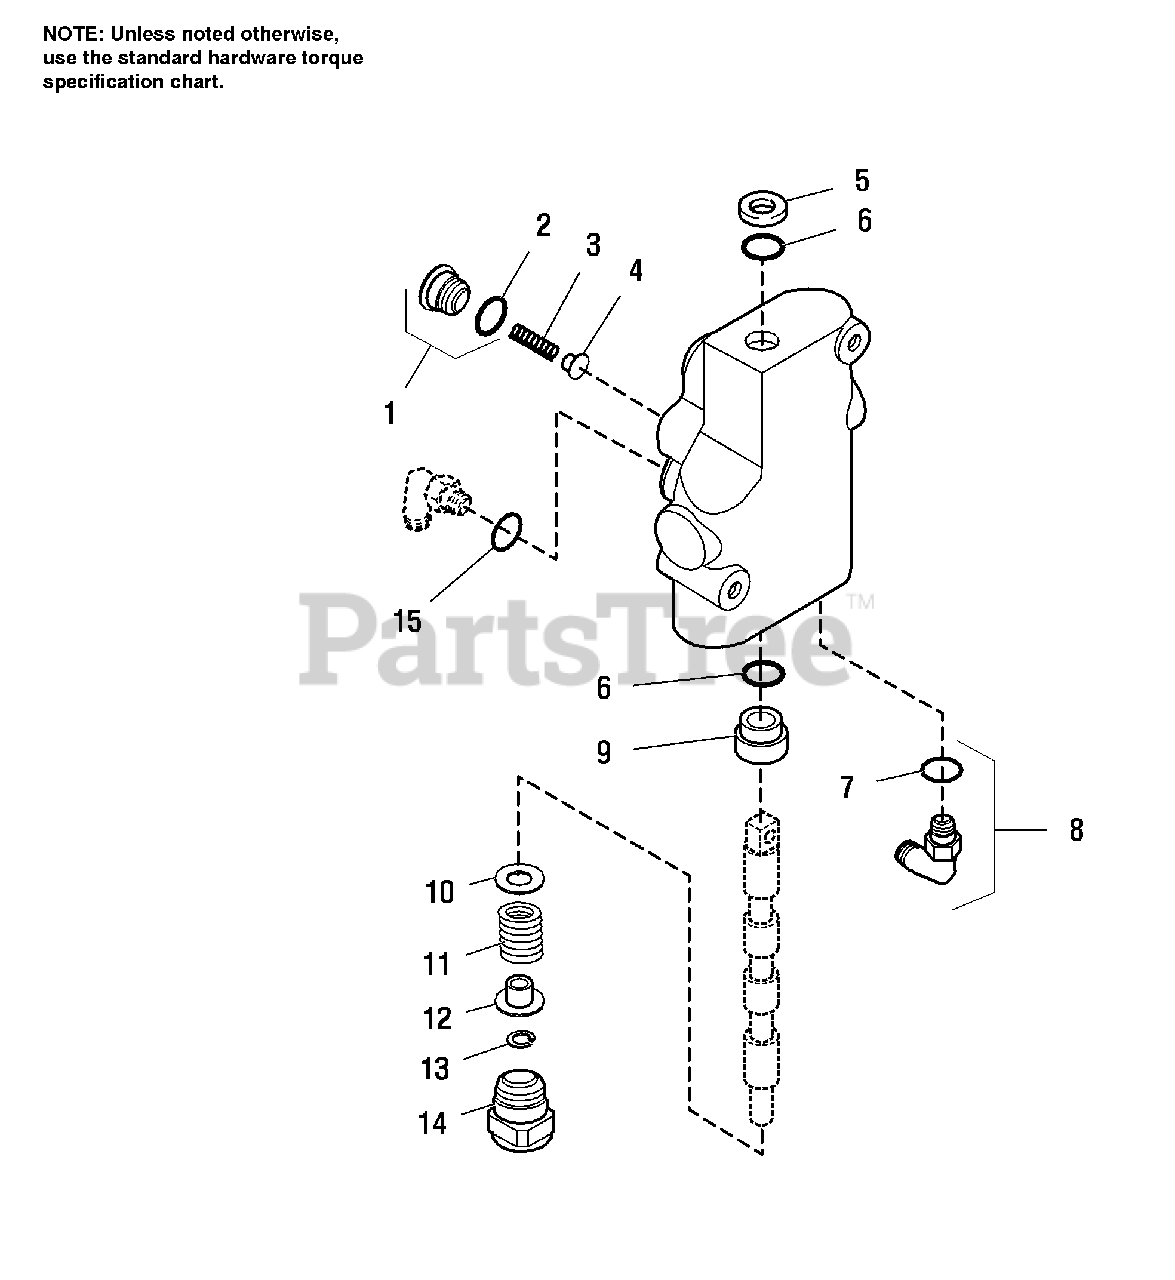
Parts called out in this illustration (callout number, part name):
1	PLUG ASSEMBLY
2	O-RING
5	WIPER PLUG
6	O-RING
7	O-RING
8	FITTING, 90°.
12	SPACER
13	RETAINING RING
14	CAP ASSEMBLY
15	O-RING
